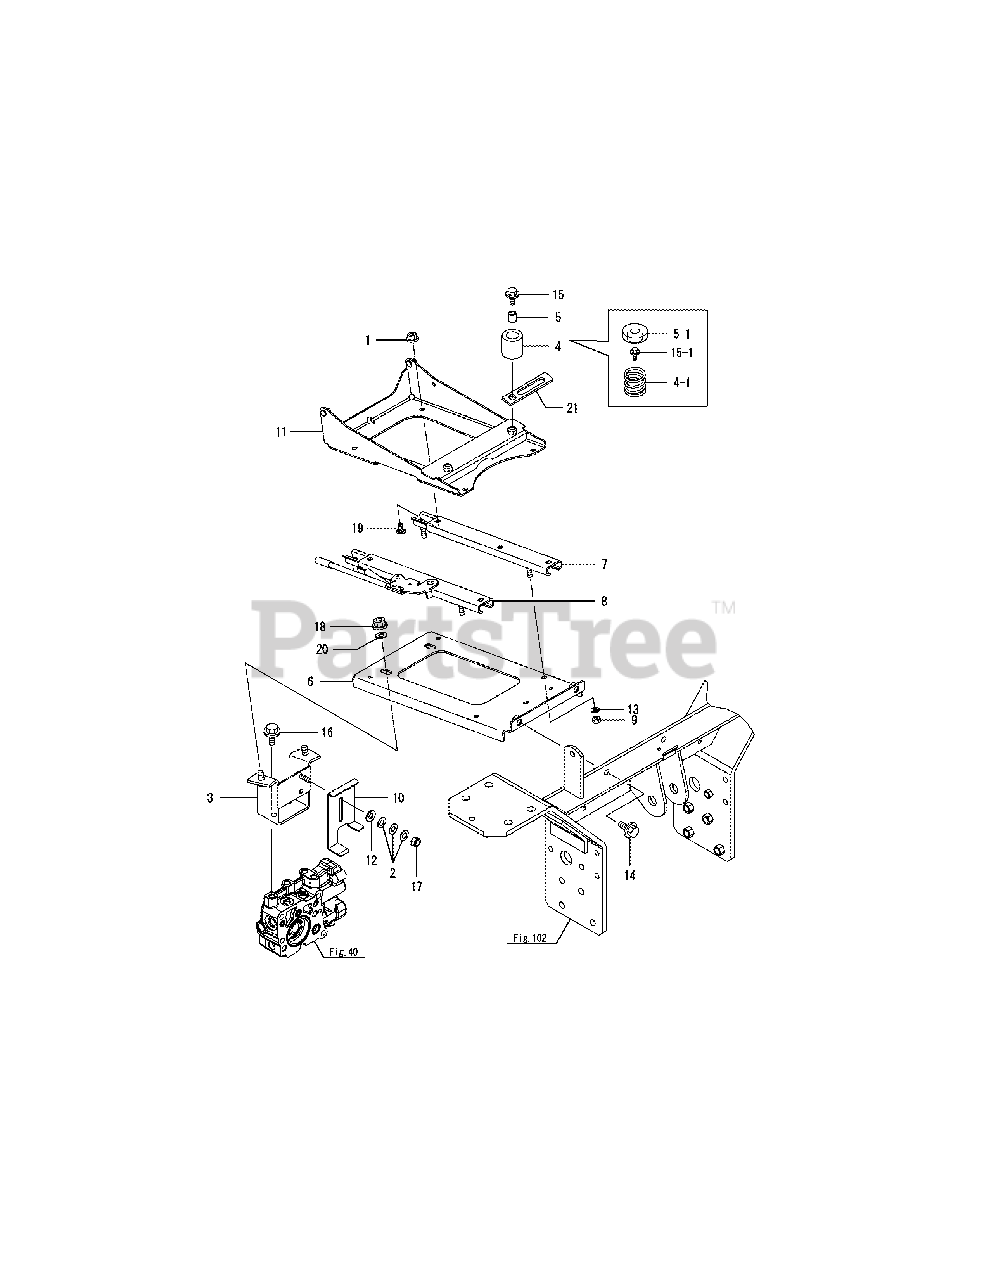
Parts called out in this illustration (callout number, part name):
1	Nut W/Washer 8
2	Spring, Conical
3	Stay (Seat Cmp
4	Rubber, Cushion
4-1	Spring
5-1	Stopper, Seat
6	Stay Cmp, Rail A
7	Rail Cmp, Seat
8	Rail Cmp, Seat Lever
9	Unc Nut 5/16-18
11	Stay Cmp, Rail B
12	Washer 8, Polished
14	Bolt 10X25 W/Plw+Spw
15	Bolt M 8X 25 Plated
15-1	Bolt M 8X 16 Plated
16	Bolt M10X 16 Plated
20	Washer 10, Polished
21	Clamp, Wire Harness
